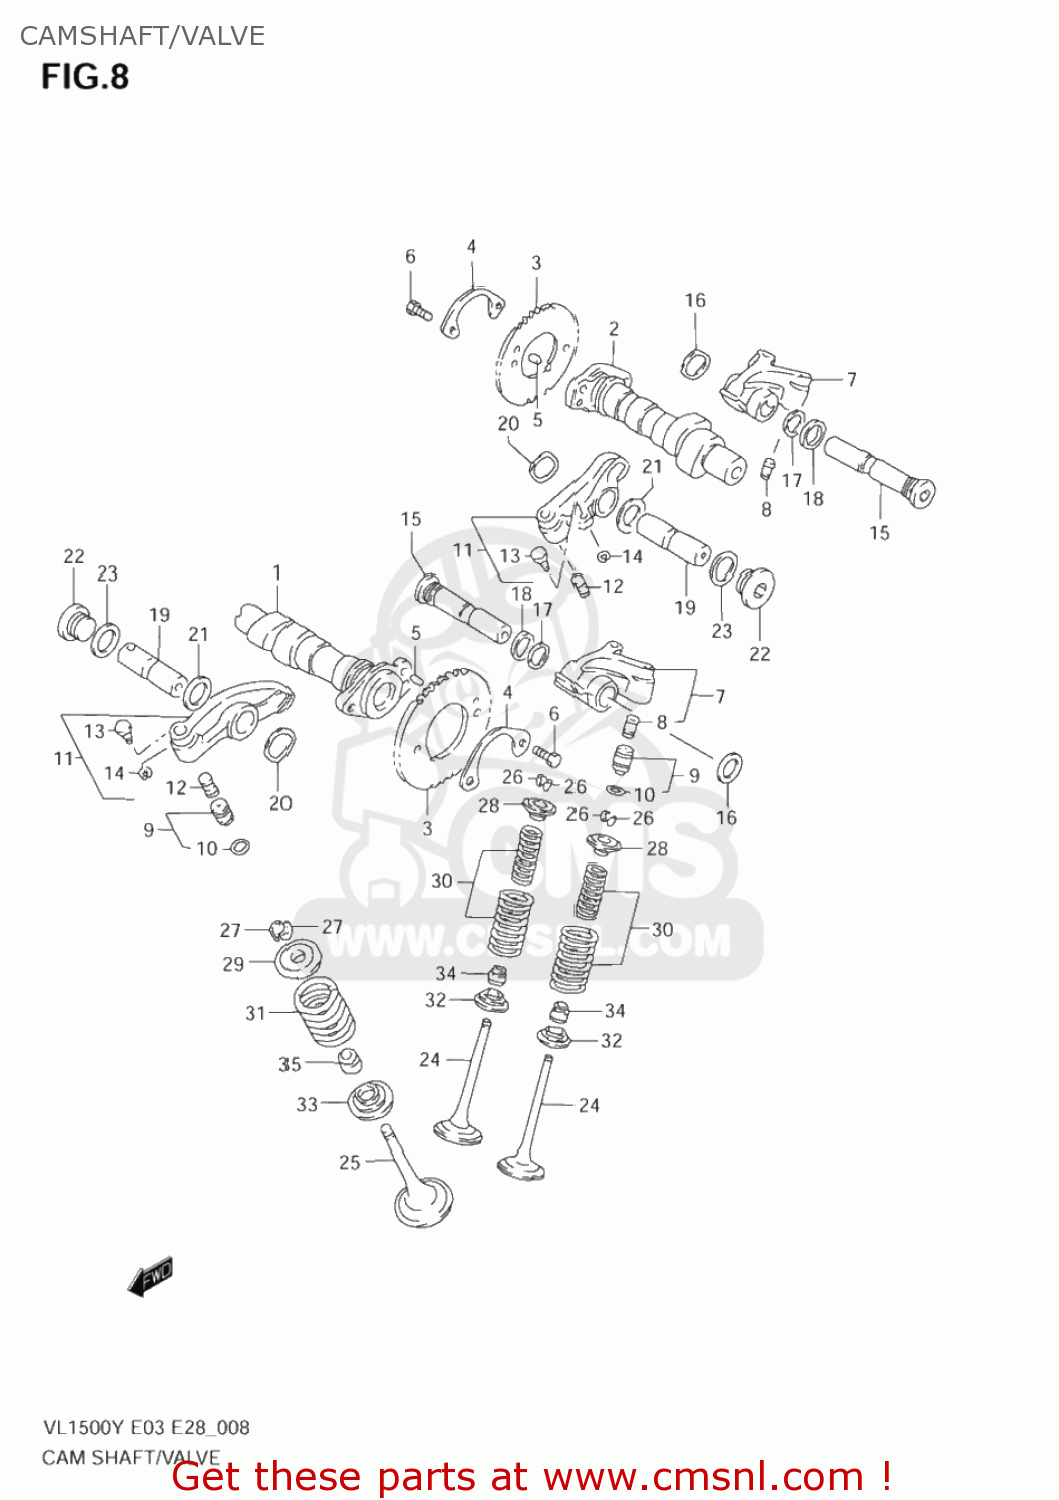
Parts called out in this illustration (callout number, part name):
1	CAMSHAFT,FR
2	CAMSHAFT,RR
3	SPROCKET,CAMSHAFT
4	WASHER,CAM CHAIN SPROCKET
5	PIN
6	BOLT(6X12.5)
7	ARM,VALVE ROCKER INTAKE
8	CHAMBER,VALVE LASH ADJUSTER
9	ADJUSTER,HYDRAULIC VALVE LASH
10	O RING
11	ARM,VALVE ROCKER FR EXHAUST
12	CHAMBER,VALVE LASH ADJUSTER
13	PIN,DECOMP
14	E RING
15	SHAFT,INTAKE VALVE ROCKER ARM
16	WASHER
17	SHIM(14X20X1)
18	GASKET(16X22X2) (NAS)
19	SHAFT,EXHAUST VALVE ROCKER ARM
20	WASHER
21	WASHER(16X26X1)
22	PLUG,18X11
23	GASKET(18X24.2X2) (NAS)
24	VALVE,INTAKE
25	VALVE,EXHAUST
26	COTTER,VALVE
27	COTTER,VALVE
28	RETAINER,VALVE SPRING
29	RETAINER,VALVE SPRING
30	SPRING SET,VALVE
31	SPRING,VALVE OUTER
32	SEAT,VALVE SPRING
33	SEAT,VALVE SPRING
34	SEAL,OIL(5.5X11X8.2)
35	SEAL,OIL(7X14.4X9)
